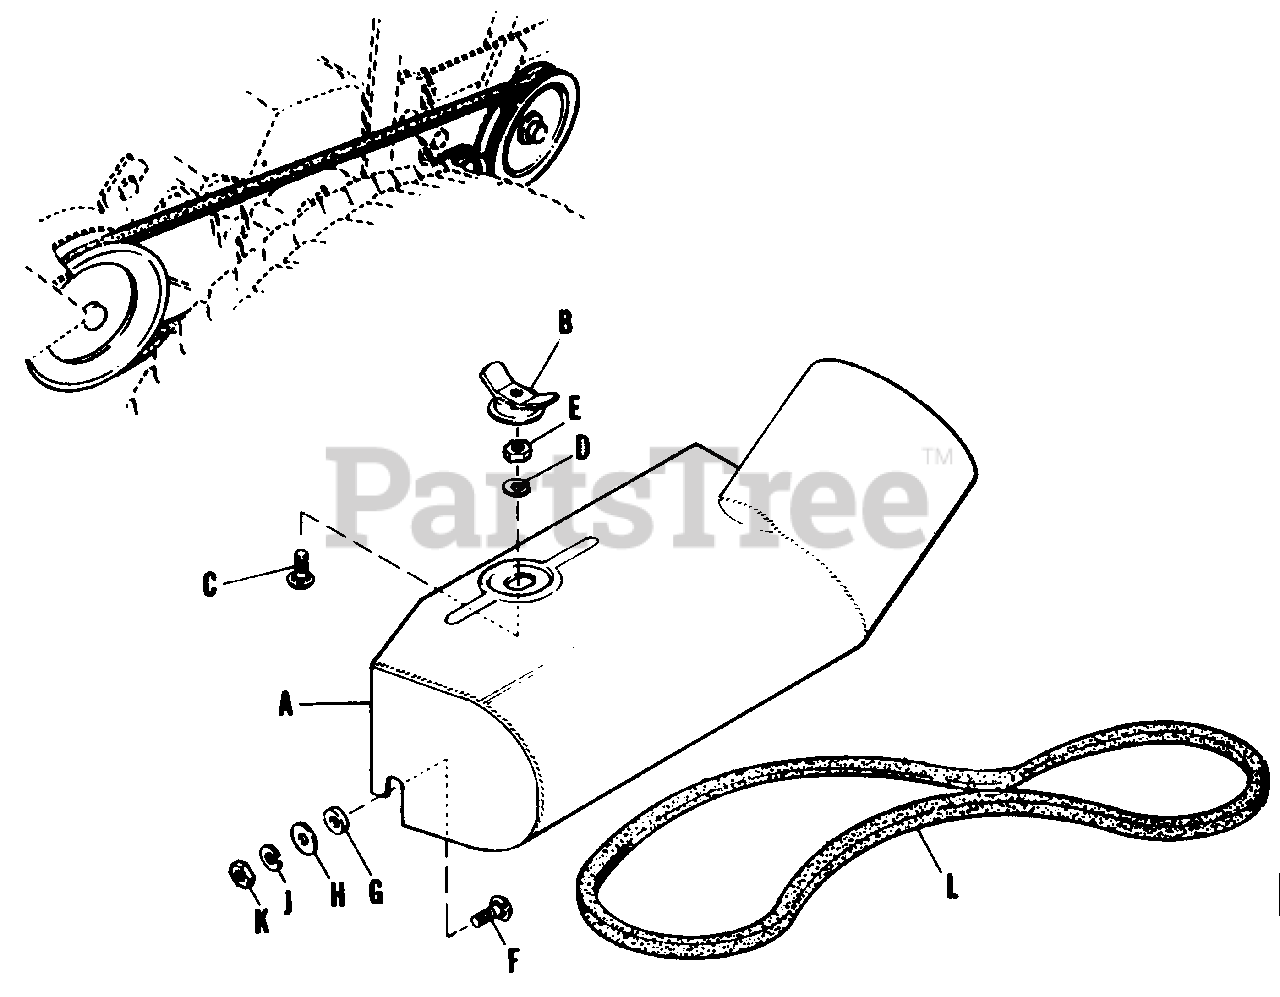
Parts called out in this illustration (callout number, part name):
A	Adaptor Assembly
B	Nut Assembly
C	Carriage Bolt, 3/8"-16 x 1" lg.
D	Lock Washer, 3/8"
E	Nut, Hex, Full, 3/8"-16
F	Carriage Bolt, 3/8"-16 x 1-1/4" lg.
J	Lock Washer, 3/8"
K	Nut, Hex, Full, 3/8"-16
L	"V" Belt
